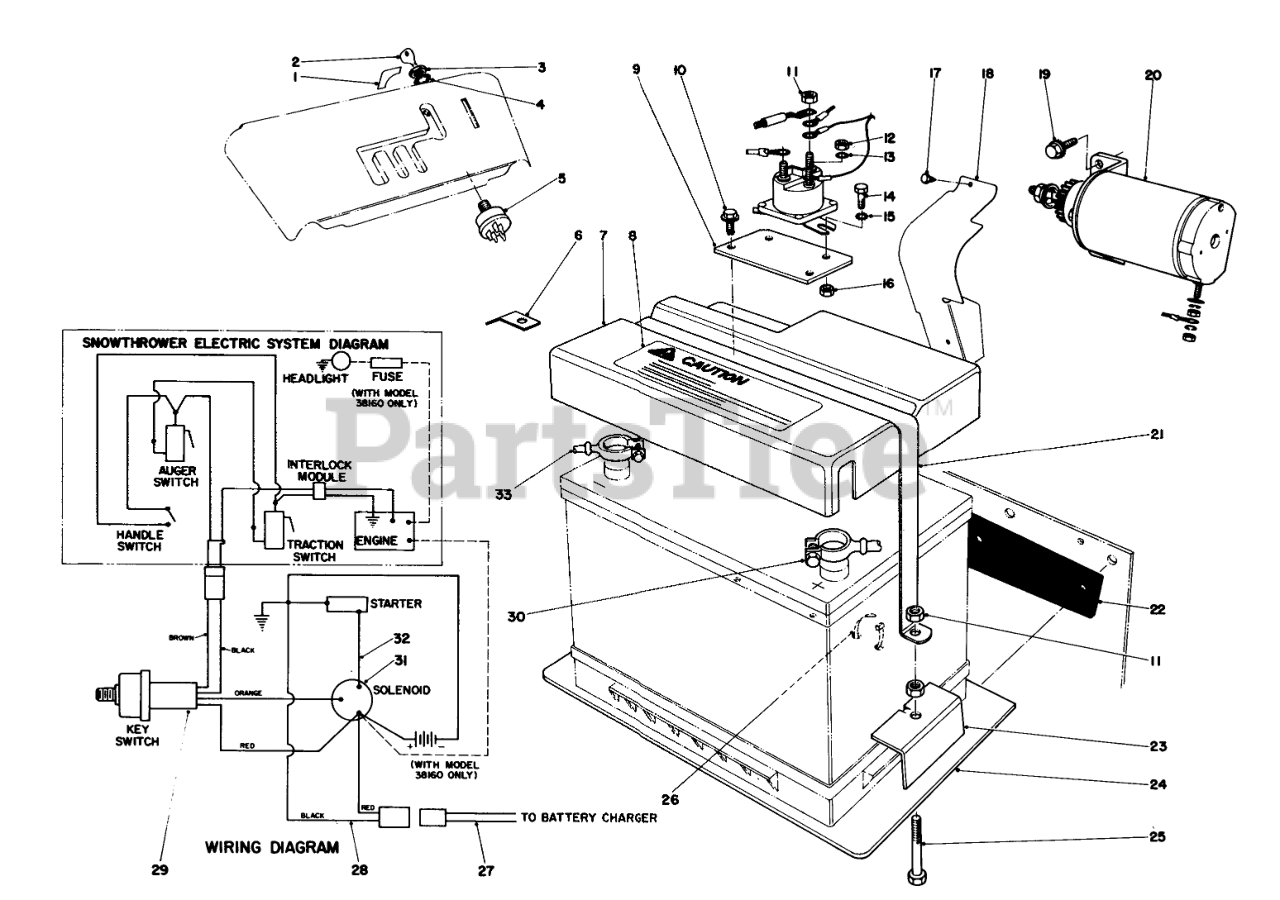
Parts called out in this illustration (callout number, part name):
1	Decal Switch
2	Key
3	NUT-HH
4	WASHER-TOOTH, INTERNAL
5	Smarter Switch
6	Bracken Wire Clamp
7	Battery Cover (Incl. Ref. #8)
8	Decal-Caution
9	Bracket Solenoid
10	SCREW-HWH
11	NUT-HEX
12	NUT-HEX
13	WASHER-LOCK, INT
14	SCREW-HH
15	WASHER-LOCK/EXT
16	NUT-LOCK, NI
17	Hex Hd. Sems Screw
18	Pinion Shield
19	Screw-HH
20	Starter Motor & Pinion Assy.
21	Strap Battery
22	Batery Isolation Pad
23	BATTERY CLAMP
24	Battery Mounting Plate
25	SCREW-HH
26	TIE-CABLE
27	MALE WIRE ASM
28	FEMALE WIRE ASM
29	Wire Harness
30	BATT-SOLENOID CABLE
31	SOLENOID
32	STRT MTR-SOLNOID WIRE
33	BATT-GROUND CABLE
